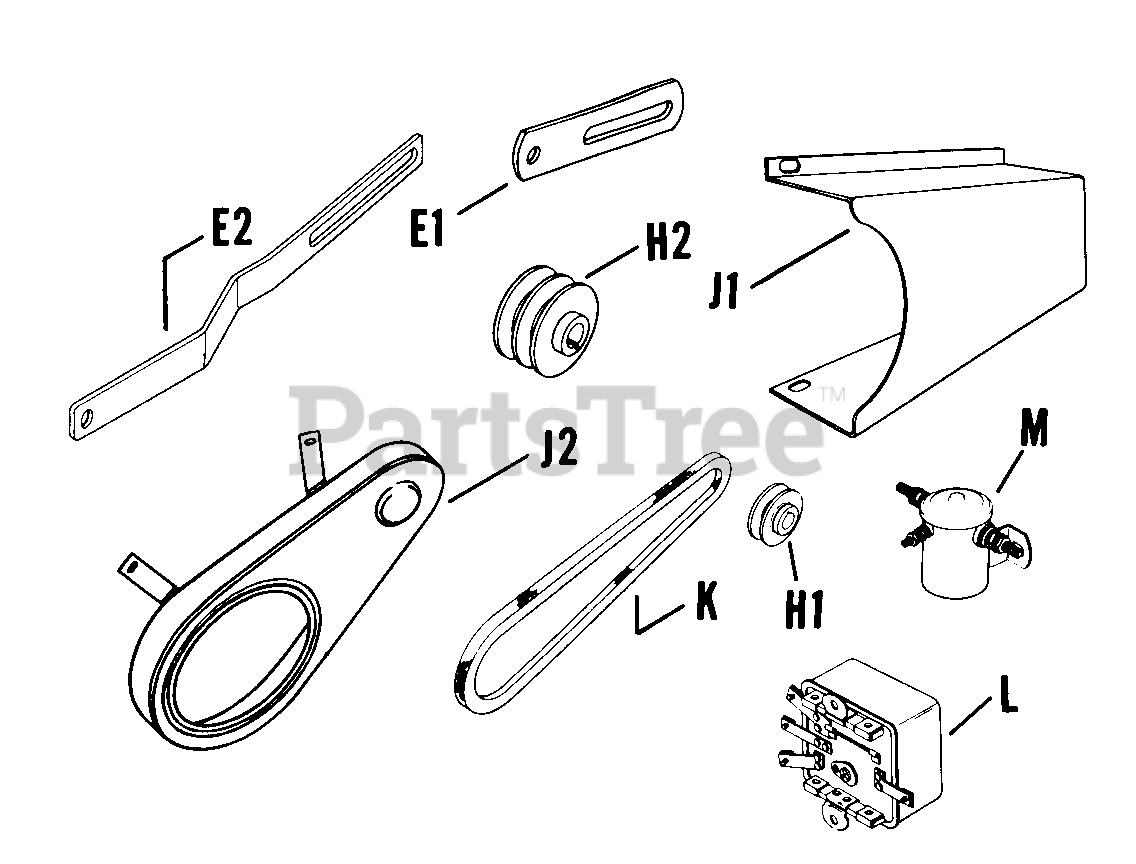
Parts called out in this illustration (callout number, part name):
H1	PULLEY - DISCONTINUED
J1	GUARD - DISCONTINUED
K	BELT - DISCONTINUED
